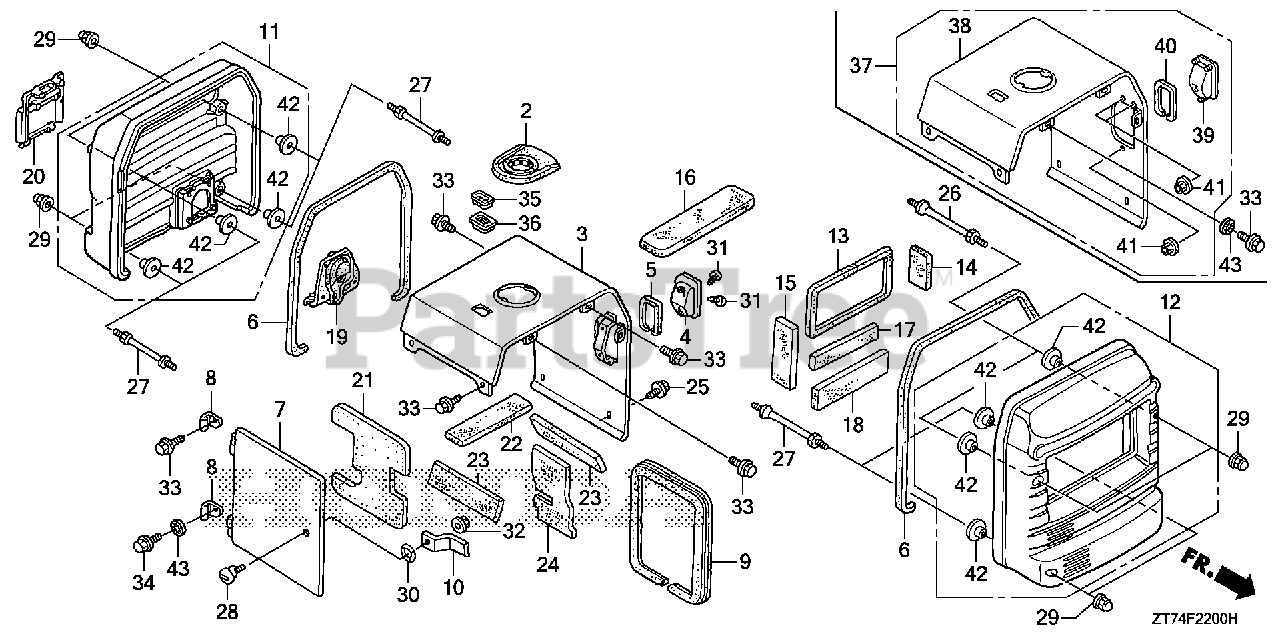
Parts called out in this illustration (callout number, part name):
2	SEAL, FUEL FILLER NECK
6	SEAL, MAIN COVER
7	COVER, MAINTENANCE *R280* (POWER RED)
8	HINGE, MAINTENANCE COVER *R280* (POWER RED)
9	SEAL, MAINTENANCE COVER
10	PLATE, MAINTENANCE LID LOCK
11	COVER, RR. *NH314* (CONDUCT GRAY)
12	COVER, FR. *NH314* (CONDUCT GRAY)
13	SEAL A, FR. COVER
14	INSULATOR, R. FR. COVER
15	INSULATOR, L. FR. COVER
16	INSULATOR A, FR. COVER
17	INSULATOR B, FR. COVER
18	INSULATOR C, FR. COVER
19	RUBBER, OIL CHECK HOLE
20	COVER, OIL CHECK *NH314* (CONDUCT GRAY)
21	INSULATOR A, MAINTENANCE COVER
22	INSULATOR A, MAIN COVER
23	INSULATOR B, MAIN COVER
24	INSULATOR C, MAINTENANCE COVER
25	BOLT, FLANGE (6X12)
26	BOLT, STUD
27	BOLT, STUD
28	BOLT, MAINTENANCE LID LOCK
29	NUT, OPEN STAY (6MM)
30	WASHER, WAVE (12MM)
32	NUT, FLANGE (6MM)
33	BOLT, FLANGE (6X10)
34	BOLT, FLANGE (6X12) Use up to Engine SN 1543277.
35	CAP, FUEL METER
36	SEAL, METER CAP
37	COVER ASSY., MAIN *R280* (POWER RED)
38	COVER, MAIN *R280* (POWER RED)
39	CASE, RECOIL GRIP *NH105* (MAT BLACK)
40	SEAL, MAIN COVER
41	NUT, FLANGE (6MM)
42	COLLAR, AIR CLEANER (TOYO ROKI)
